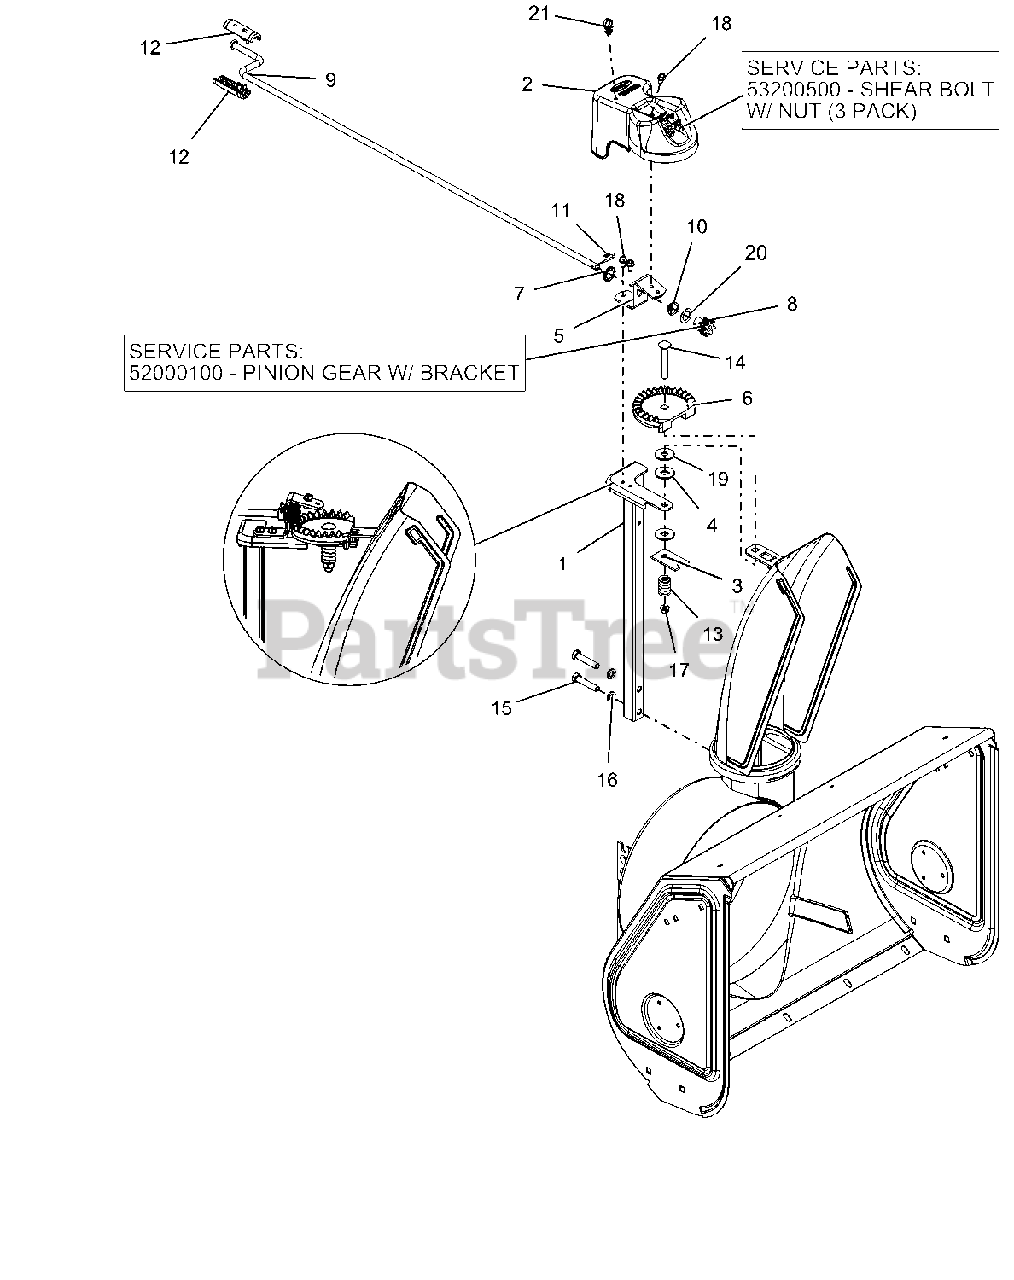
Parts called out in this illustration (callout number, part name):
1	CHUTE PEDESTAL, TALL COMPACT
2	GEAR COVER ASSY SM SHEAR BOLT
3	PLATE, FRICTION
4	FRICTION WASHER
5	BRACKET, PINION GEAR
6	CHUTE GEAR
7	PUSHNUT .625
8	PINION GEAR - CHUTE
9	ROD, CHUTE CRANK, COMP&SNOTEK
10	BUSHING, POLYLINER-.63 SNAPIN
11	PIN, SPRING CLIP
12	KNOB,CRANK-SNAP COMPACT-GRAY
13	SG-COMP .187X.56X1.62
14	@BLT-RDHDSQNK .38-16X2.50 G5YZ
15	@BLT-HEX .38-16X1.75 GR5 YWZC
16	@WSHR-LK .38X.094 REG YWZC
17	@NUT-LK-TOP-FLG .25-20 YWZC
18	SCR-TAP .25-20X.50 HWH TR YWZ
19	@WSHR-FL-STL .406X1.25X.10 ZC
20	WSHR-THRST .625 X 1.0 X .03
21	CLIP, CABLE GUIDE
22	SHEAR BOLT WITH NUT
23	PINION GEAR W/BRACKET
